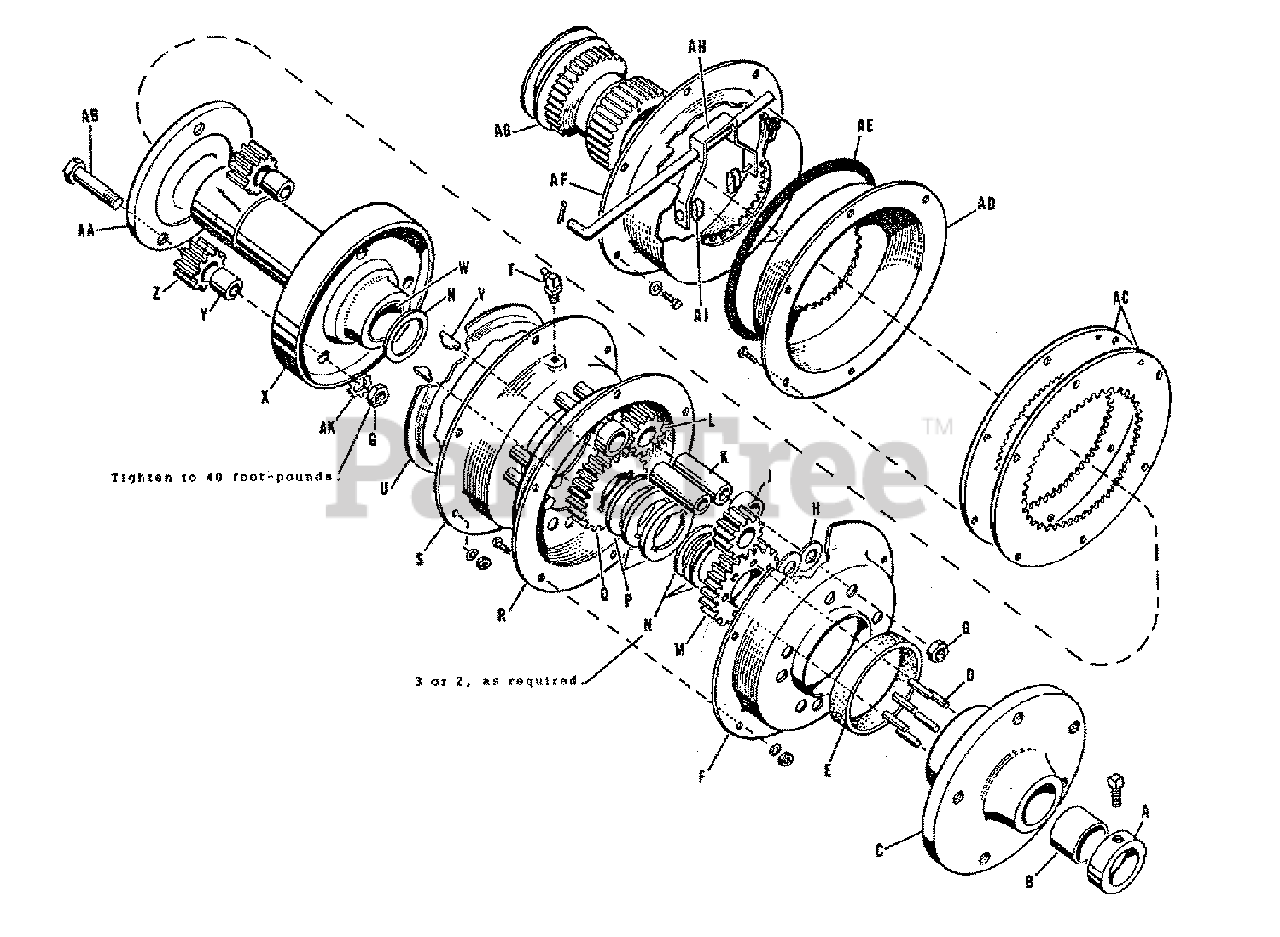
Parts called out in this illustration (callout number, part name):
A	COLLAR, Set
C	HUB, Wheel, R.H.
D	PIN, Roll
E	SEAL, Differential Cover
F	COVER, Differential
G	NUT, Lock, Full Hex, 3/8-24
H	WASHER, Plain, 5/16"
J	SPACER, Differential
K	SPINDLE, Pinion, Differential
L	PINION, Differential
M	GEAR, Differential
P	WASHER, Axle
Q	GEAR, Differential
R	COVER, Differential
S	CARRIER ASSEMBLY
T	FITTING, Grease, Alemite #1637
U	PLATE, Thrust
V	KEY, Hi-Pro, HP-608
X	SPIDER ASSEMBLY
Y	SPACER, Pinion
AA	RING, Bolt
AC	GEAR, Ring
AD	COVER ASSEMBLY
AE	SEAL, Housing Assembly
AF	HOUSING ASSEMBLY
AG	GEAR ASSEMBLY, Sun
AH	CLEVIS ASSEMBLY
AJ	BLOCK, Shift
AK	LOCKWASHER, External Shakeproof
